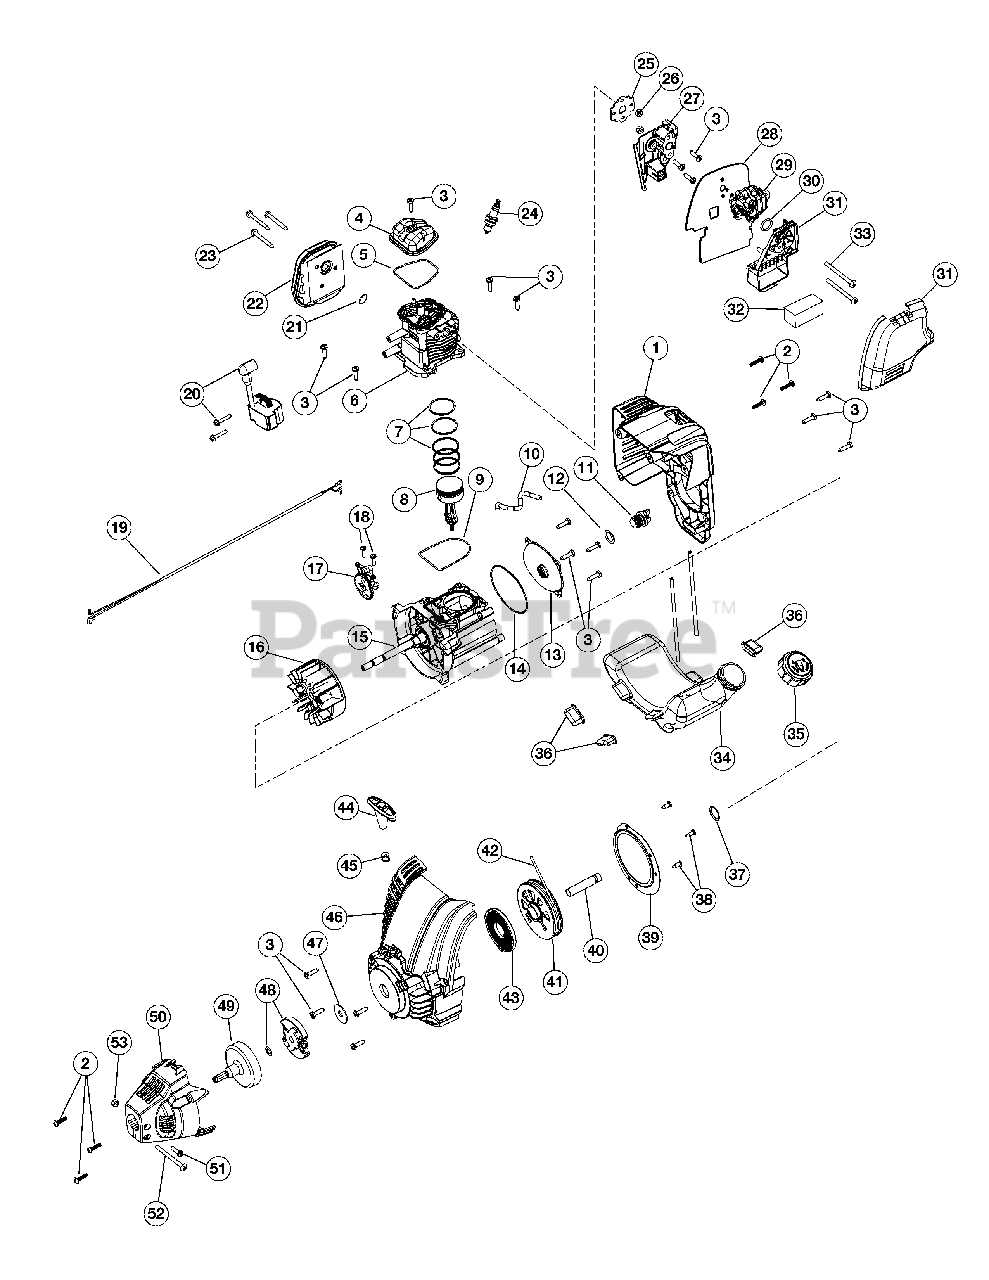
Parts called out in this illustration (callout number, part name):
1	Engine Cover Assembly (includes 2 & 3)
2	Cover Screw
3	Screw
4	Rocker Cover
5	Rocker Cover O-Ring
6	Cylinder Assembly (includes 3, 5 & 9)
7	Piston Ring Assembly
8	Piston Assembly (includes 7)
9	Cylinder O-Ring
10	Breather Hose
11	Oil Plug (includes 12)
12	Oil Plug O-Ring
13	Crankcase Cover
14	Crankcase Cover O-ring
15	Crankcase Assembly (includes 9, 10, 14 & 16)
16	Flywheel Assembly
17	Cam Bracket Assembly (includes 18)
18	Cam Bracket Screw
19	Lead Wires
20	Module Assembly
21	Muffler Gasket
22	Muffler Assembly (includes 21 & 23)
23	Muffler Screw
24	Spark Plug
25	Insulator Gasket
28	Carburetor Gasket
29	Carburetor w/Primer
31	Air Cleaner Cover Assembly (includes 32)
32	Air Filter
34	Fuel Tank Assembly w/Fuel Lines (includes 35)
36	Fuel Tank Pads
38	Pressure Plate Screw
39	Pressure Plate (includes 38)
41	Starter Assembly (includes 42)
43	Recoil Spring
44	Handle
46	Starter Housing Assembly (includes 3 & 37-45)
48	Clutch & Clutch Washer
49	Clutch Drum
50	Clutch Cover
51	Anti-Rotation Screw
52	Clamp Screw
53	Nut
